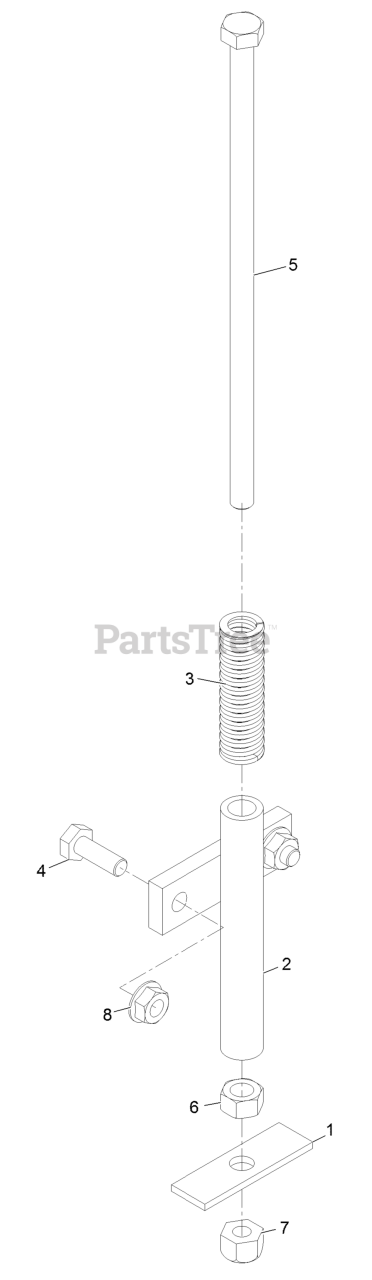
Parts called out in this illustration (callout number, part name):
1	PLATE-SWITCH, SEAT
2	MOUNT-SPRING, SEAT
3	SPRING-SWITCH, SEAT
4	SCREW-HH
5	SCREW-HH
6	NUT-HEX
7	NUT-LOCK, NI
